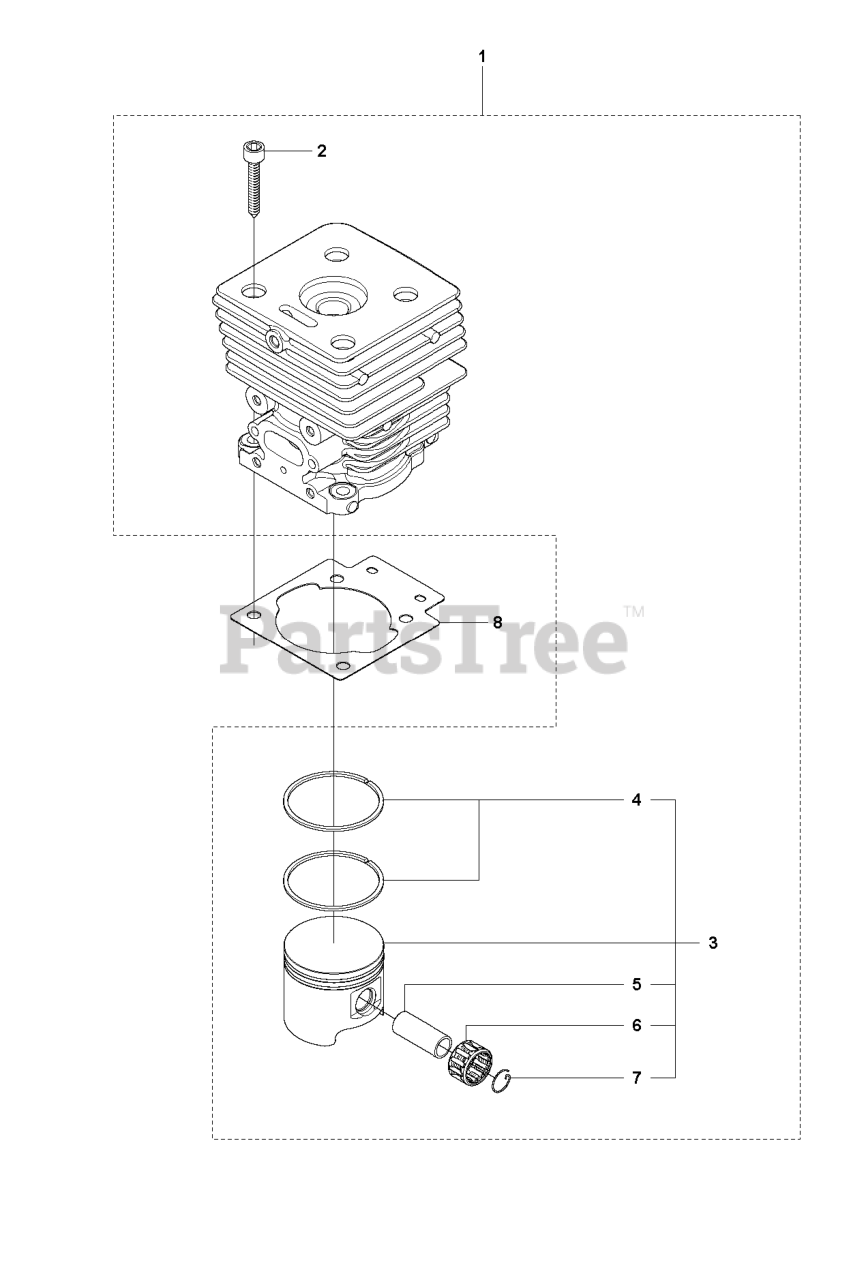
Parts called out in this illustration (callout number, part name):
1	CYLINDER ASSY
2	SCREW
3	PISTON ASSY D41 SPARE PART
4	PISTON RING D41X1.7X1.2
5	PISTON PIN 10X7X32
6	NEEDLE BEARING
7	LOCKING RING
8	GASKET CYLINDER
